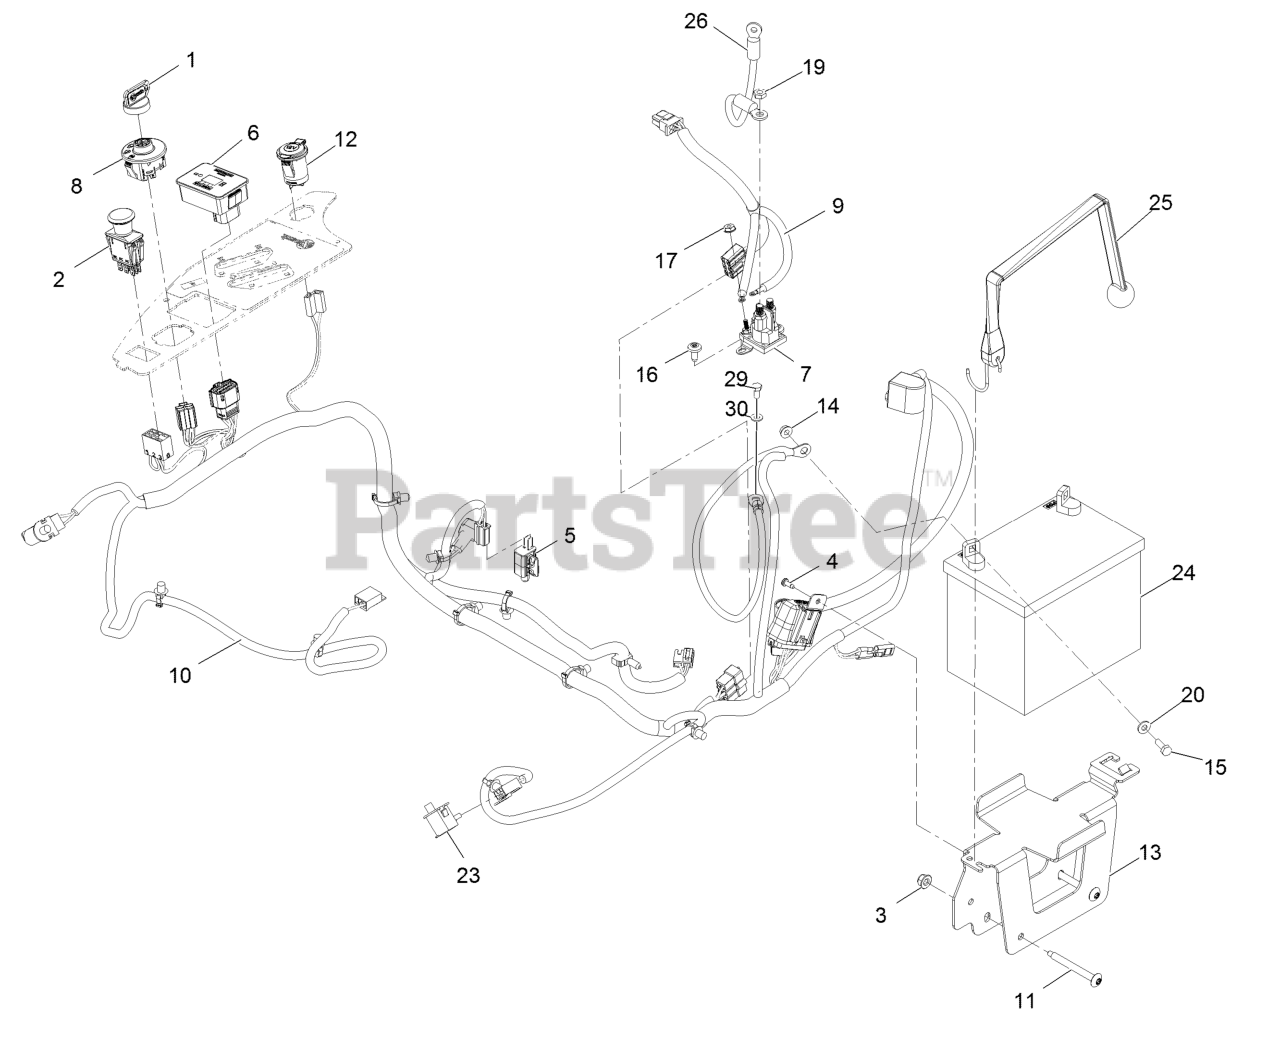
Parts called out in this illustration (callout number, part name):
1	Key-Ignition
1	Key-Exmark Logo
2	Switch-PTO
3	Nut-Nyloc 5/16-18 Flg
4	Screw-Tph #10-24 X 1/2 Tf
6	Module ASM
7	Solenoid
8	Switch-Ignition
9	Adapter-Harness, Wire
10	Harness-Wire
11	Screw-Truss HD 5/16-18 X 2 3/4 Torx Plus
12	Port-Power, 12V
13	Tray-Battery
14	Nut-Whizlock 1/4-20
15	Screw-HH 1/4-20 X 3/4
16	Screw-1/4-20 X .65 Torx Plus
17	Nut-Keps 10-32 Unf Yz
19	Nut-Jam 5/16-24
20	Washer-1/4 SAE
24	Battery (300 CCA, Wet)
25	Strap-Bungee
26	Cable-Battery, Positive
29	Screw-HH
30	Washer-5/16 SAE
